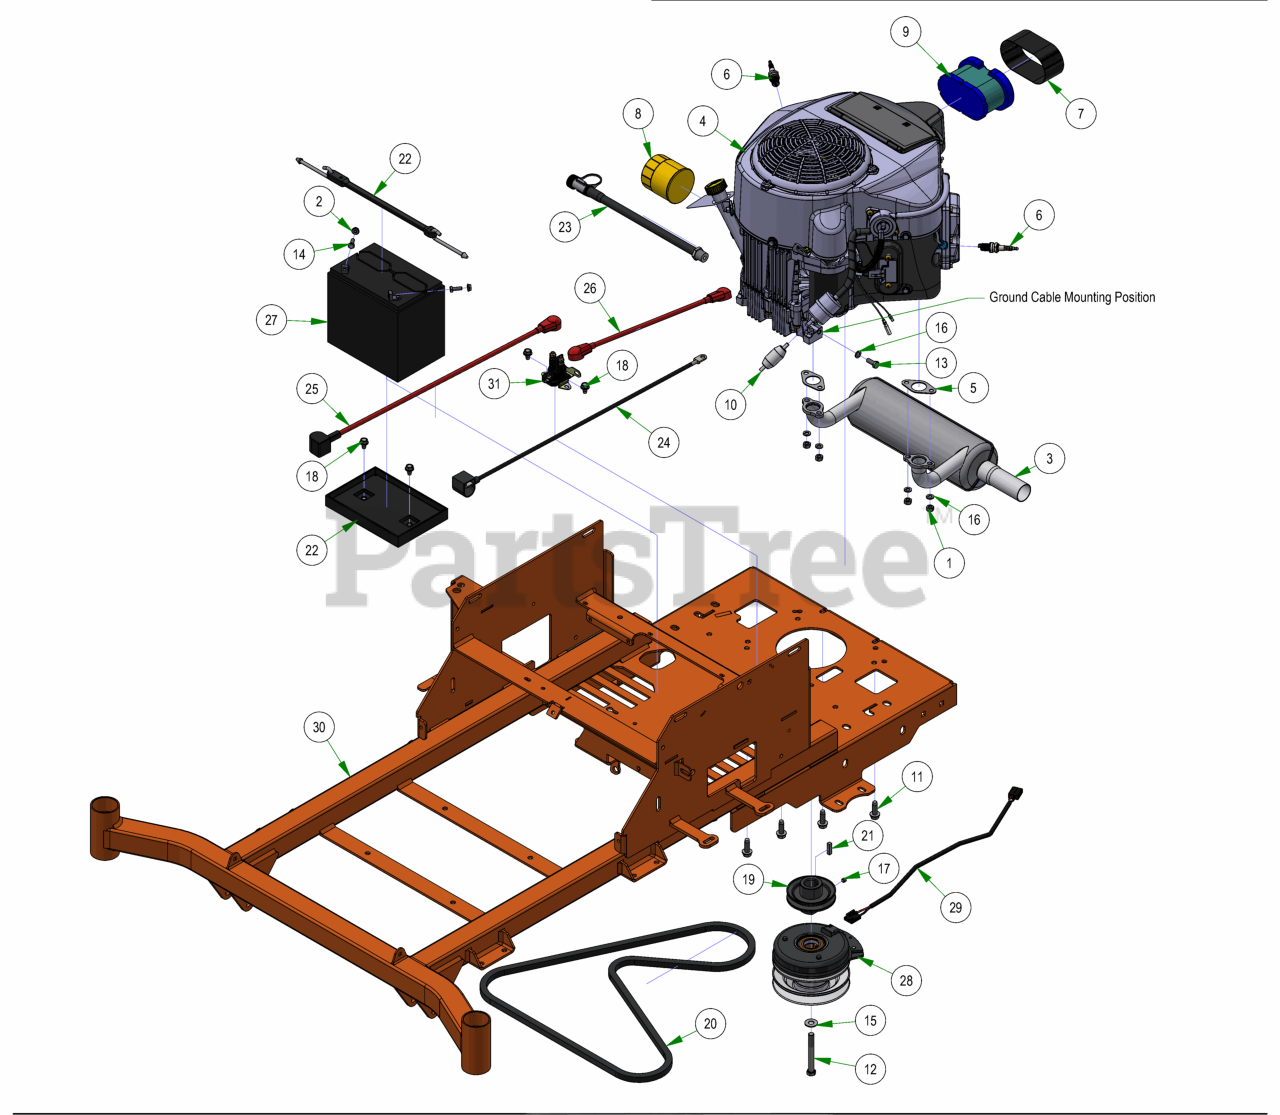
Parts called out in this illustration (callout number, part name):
1	M8-1.25 DIN 934 HEX NUT (CL.8) ZINC
2	1/4-20 HEX SERRATED FLANGE NUT HARD/ZINC
3	Kawasaki Muffler 1251
4	Kawasaki FR691 29.5HP
5	Exhaust Gasket
6	Spark Plug - Kawasaki
7	Air Filter Pre-Cleaner for KAW
8	22-26 Kaw Oil Filter FR Engine
9	Kawasaki Air Filter
10	Universal Inline Fuel Filter
11	3/8-16 X 1-1/8 HEX WASHER UNSLOT SERRATED (TRI-LOB) TRS ZINC YELLOW
12	7/16-20 x 3 1/2" Hex Bolt GR8 W/ Patch
13	M8-1.25 X 20MM DIN 933 HEX TAP BOLT (CL 8.8) ZINC
14	1/4-20 X 3/4 HEX CAP SCREW (GR.5) ZINC
15	3/8 FLAT WASHER USS (1" OD) ZINC
16	5/16 SPLIT LOCKWASHER ZINC
17	5/16-24 X 1/4 SOCKET SET SCREW (CUP PT) PLAIN
18	5/16-18 X 1/2 HWH unslot (F) tcs zinc
19	3-3/4" Motor Pulley
21	1/4 X 1 SQ MACHINERY KEY 1018 STL PLN
22	2023 Battery Hold Down Assembly
23	Kawasaki Oil Drain
24	24 inch Black Cable – MZ/ZT
25	24" Red Battery Cable
26	14" Red Battery Cable
27	SP-35 Battery
28	120 Ft Lb. Clutch - 1" Shaft
29	Clutch Pigtail
30	2025 MZ-Avenger 54-60 Frame
